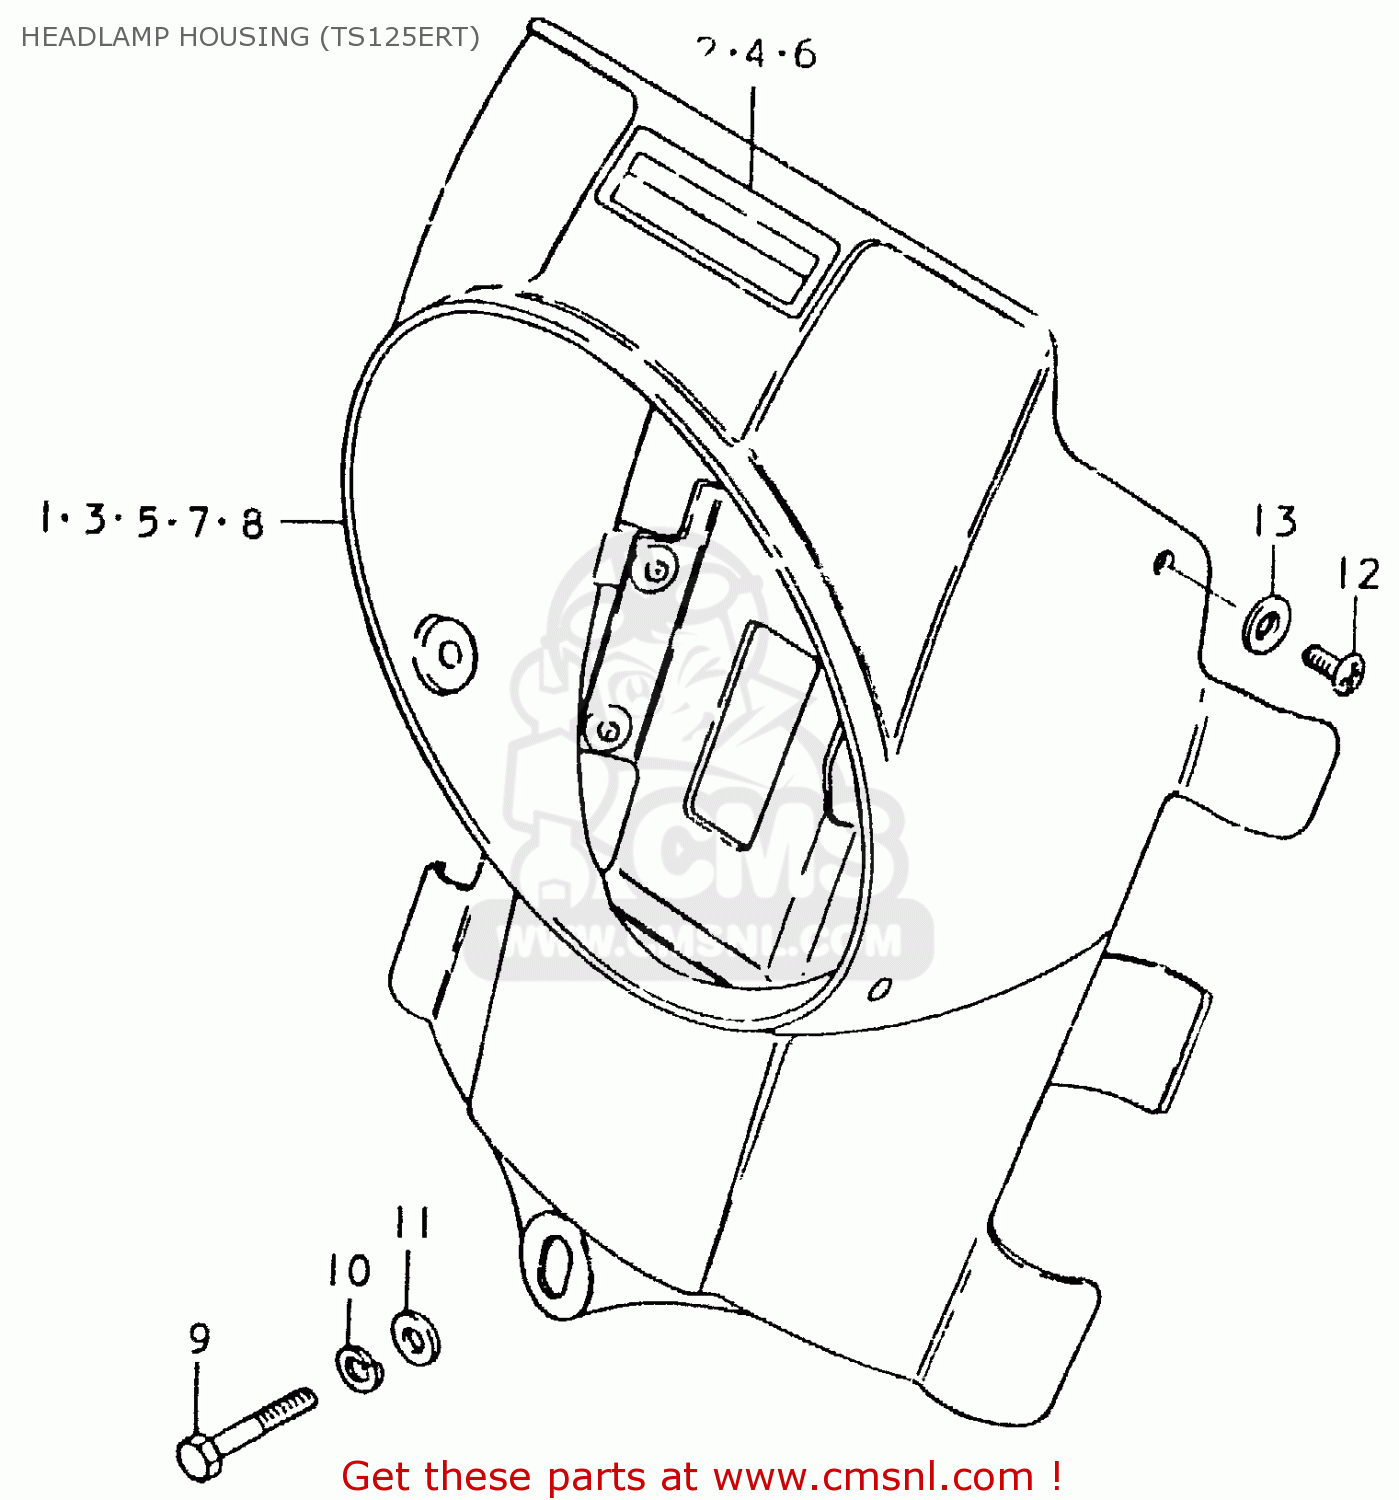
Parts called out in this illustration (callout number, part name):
1	HOUSING, HEADLAMP (RED)
2	TAPE, HOUSING
3	HOUSING,HEADLAMP
4	TAPE, HOUSING
5	HOUSING, HEADLAMP (WHITE)
6	TAPE, HOUSING
7	HOUSING,HEADLAMP
8	HOUSING, HEADLAMP (RED)
9	BOLT
10	LOCK WASHER
11	WASHER
12	SCREW
13	WASHER (5.5X16X1.2)
